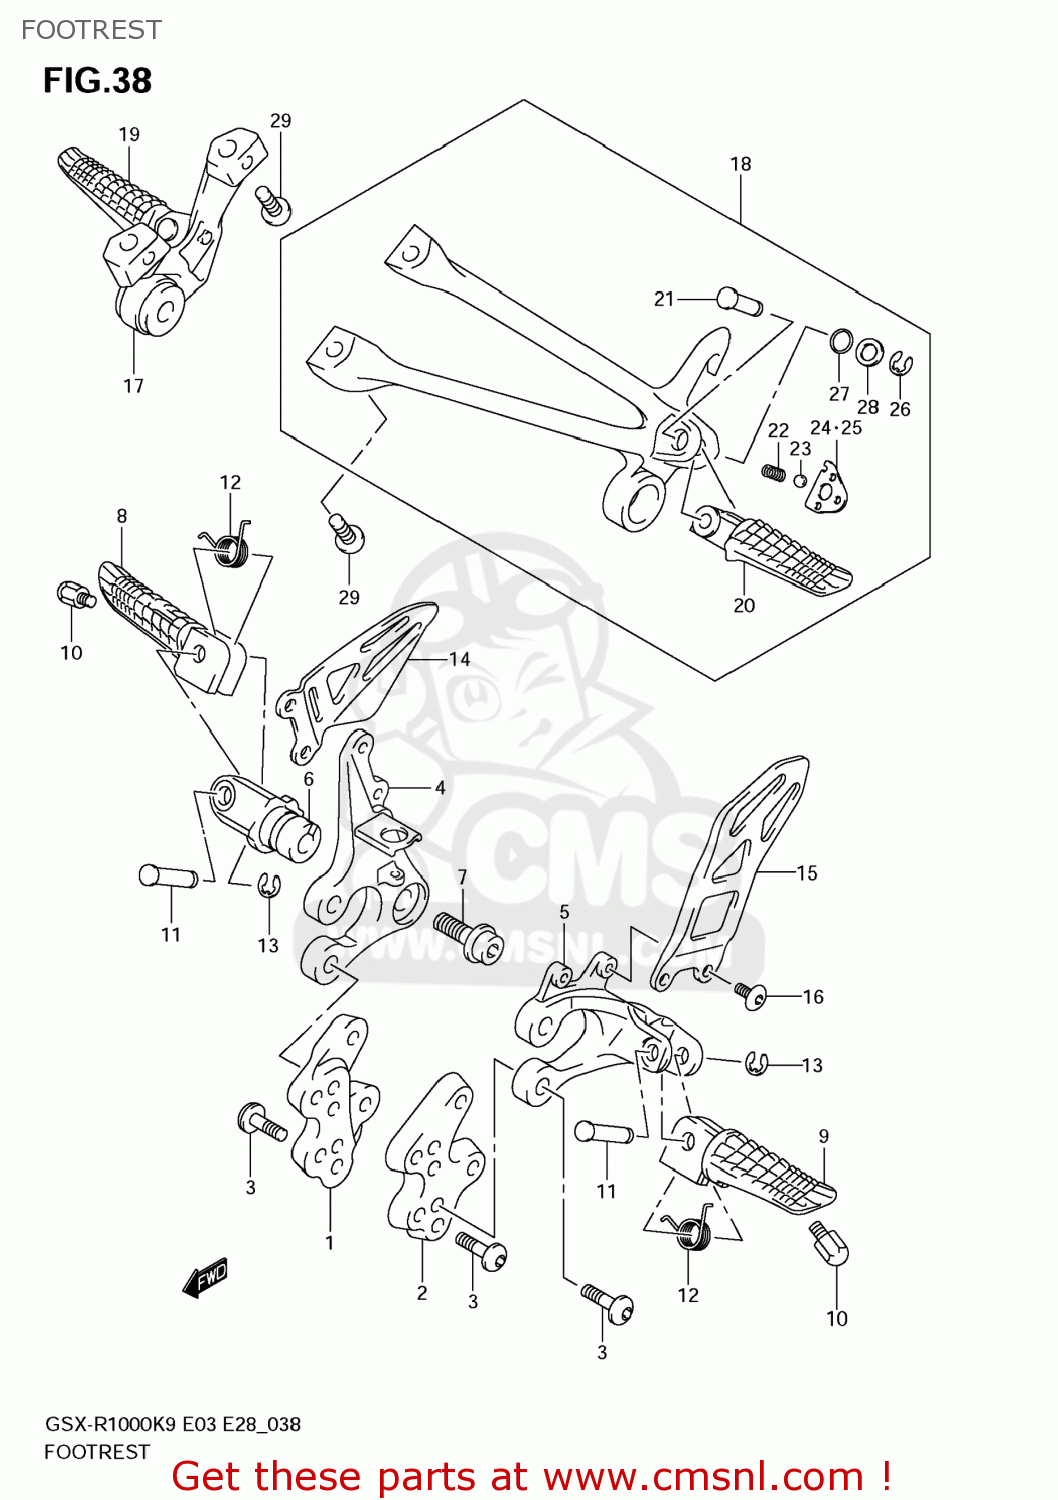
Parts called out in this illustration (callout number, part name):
1	BRACKET,FR FOOTREST NO.1,R
2	BRACKET,FR FOOTREST NO.1,L
3	BOLT(8X23)
4	BRACKET,FR FOOTREST NO.2,R
5	BRACKET,FR FOO
6	HOLDER,FOOTREST
7	BOLT(10X28)
8	BAR,FR FOOTREST,R
9	BAR,FR FOOTREST,L
10	BOLT,BANK SENSOR
11	PIN(8X33.2)
12	SPRING
13	E RING
14	GUARD,FR FOOTREST,R
15	GUARD,FR FOOTR
16	SCREW,FOOTREST GUARD,L
17	FOOTREST ASSY,PILLION,R
18	FOOTREST ASSY,PILLION,L
19	BAR,PILLION FOOTREST,R
20	BAR,PILLION FOOTREST,L
21	PIN
22	SPRING
23	BALL
24	PLATE,PILLION FOOTREST,R
25	PLATE,PILLION FOOTREST,L
26	E RING
27	O RING(D:2.4,ID:6.9)
28	WASHER(8.5X14X1.0)
29	BOLT(8X23)
